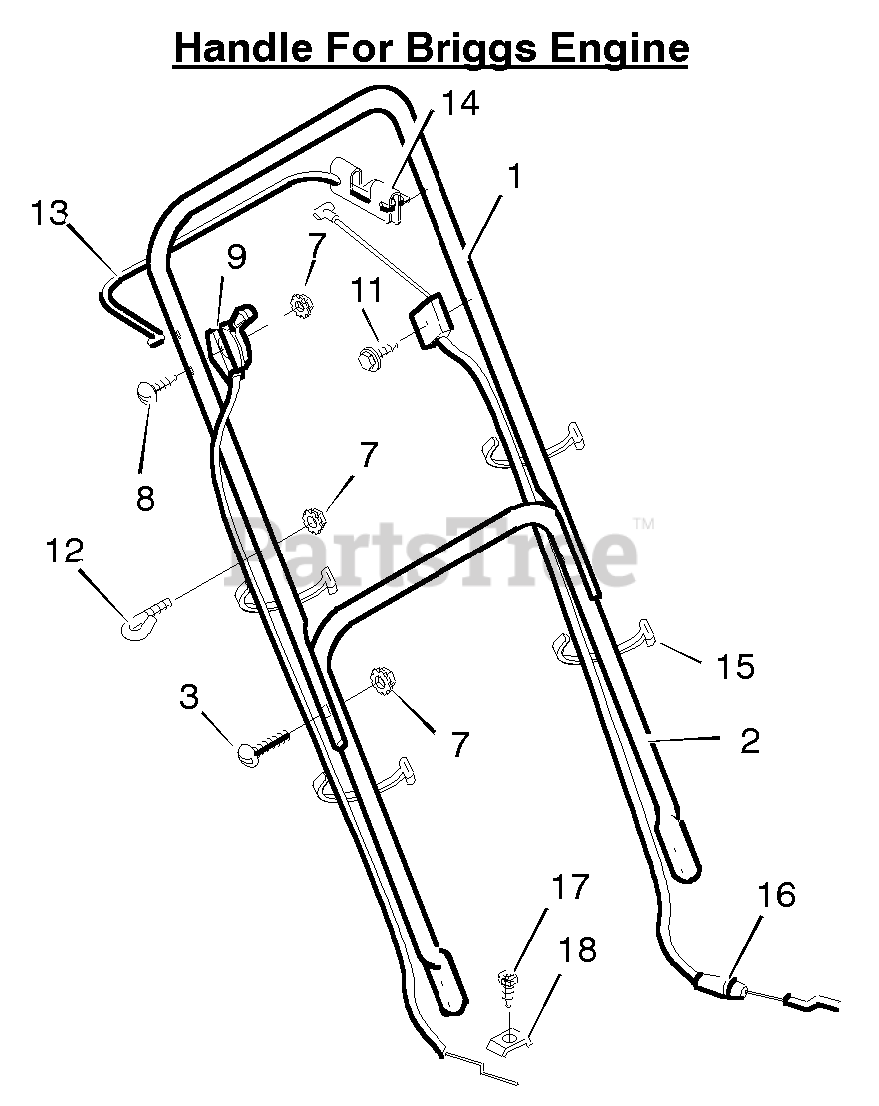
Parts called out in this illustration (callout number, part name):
1	Handle, Upper (Black)
2	Handle, Lower (Black)
7	Locknut
9	Throttle Control
12	GUIDE, ROPE
13	Engine Stop Lever
14	Bracket, Stop Lever
15	Fastener, Cable
16	Engine Stop Cable
